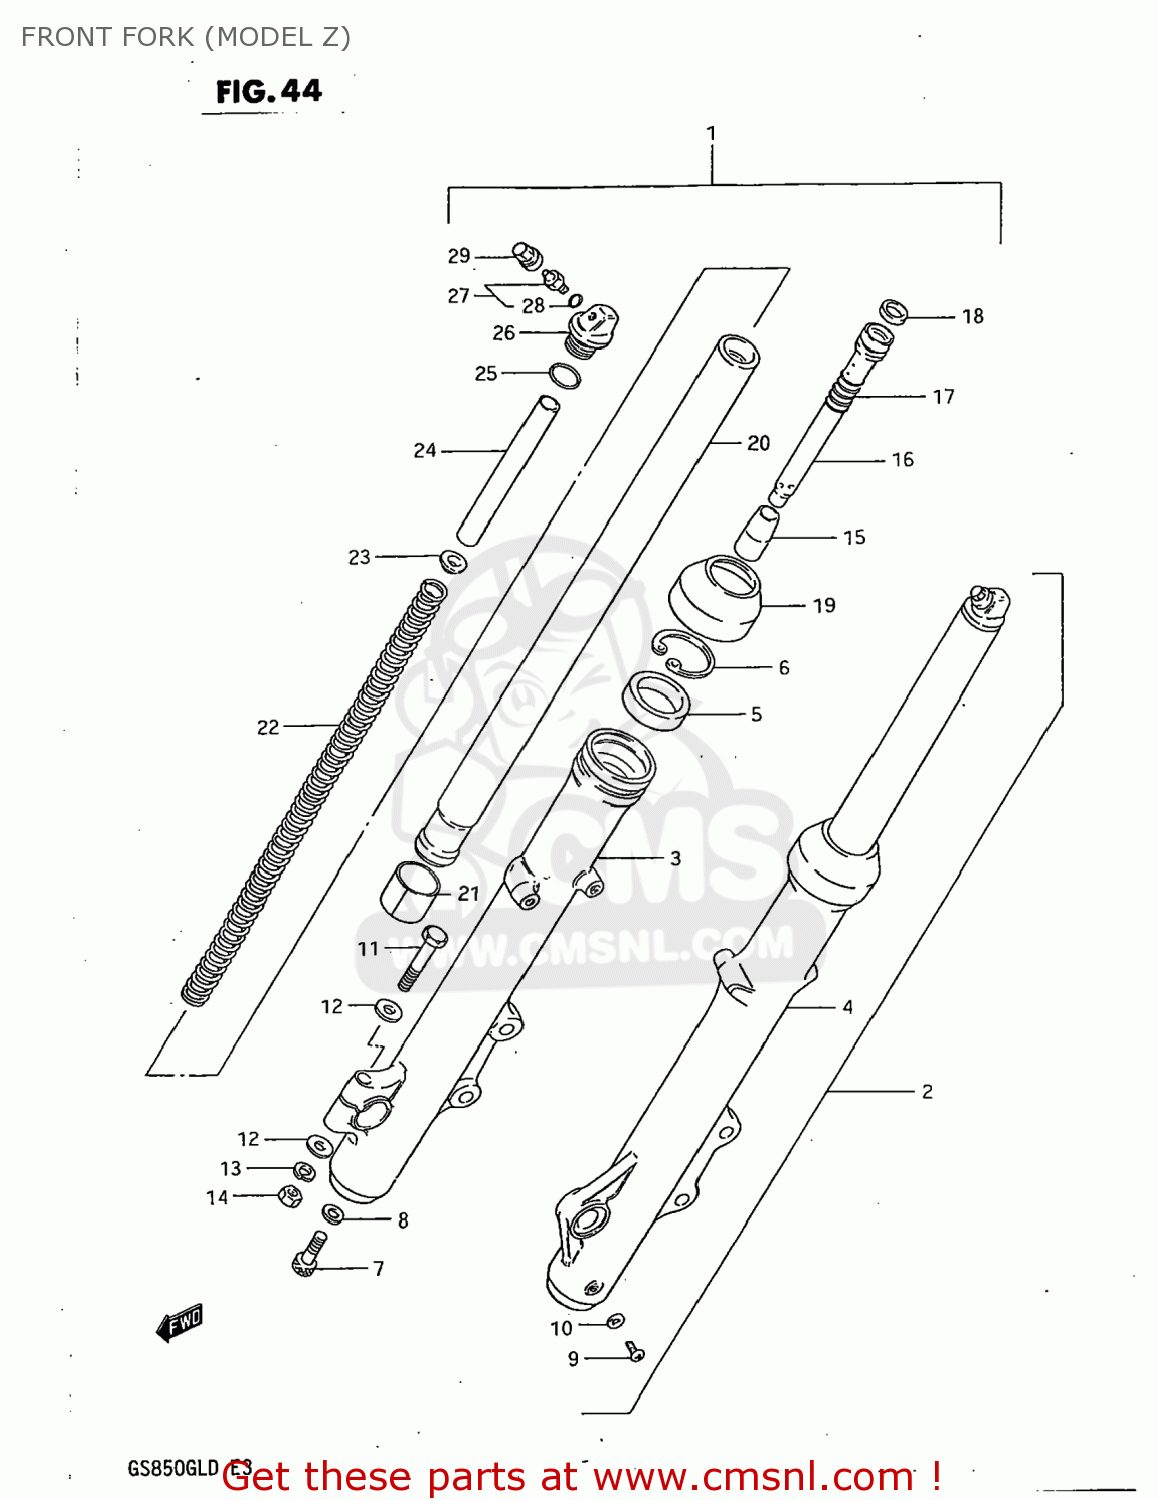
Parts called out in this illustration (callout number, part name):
1	DAMPER ASSEMBLY,RIGHT
2	DAMPER SET
3	TUBE,FORK,OUTER,RIGHT
4	TUBE,OUTER,LEFT
5	OIL SEAL,FRONT FORK
6	RING,STOPPER
7	BOLT,FORK CYLINDER(10X25)
8	GASKET (NAS)
9	SCREW
10	GASKET,DRAIN,PLUG (NAS)
11	BOLT 8X50
12	WASHER
13	WASHER,LOCK,8.
14	NUT
15	PIECE,OIL LOCK
16	CYLINDER,FRONT FORK
17	SPRING,REBOUND
18	RING,PISTON
19	SEAL,DUST
20	TUBE,INNER
21	PISTON
22	SPRING,FRONT FORK
23	GUIDE,FRONT FORK SPRING C
24	COLLAR,SPRING
25	O RING
26	CAP
27	VALVE
28	O RING
29	CAP,VALVE
